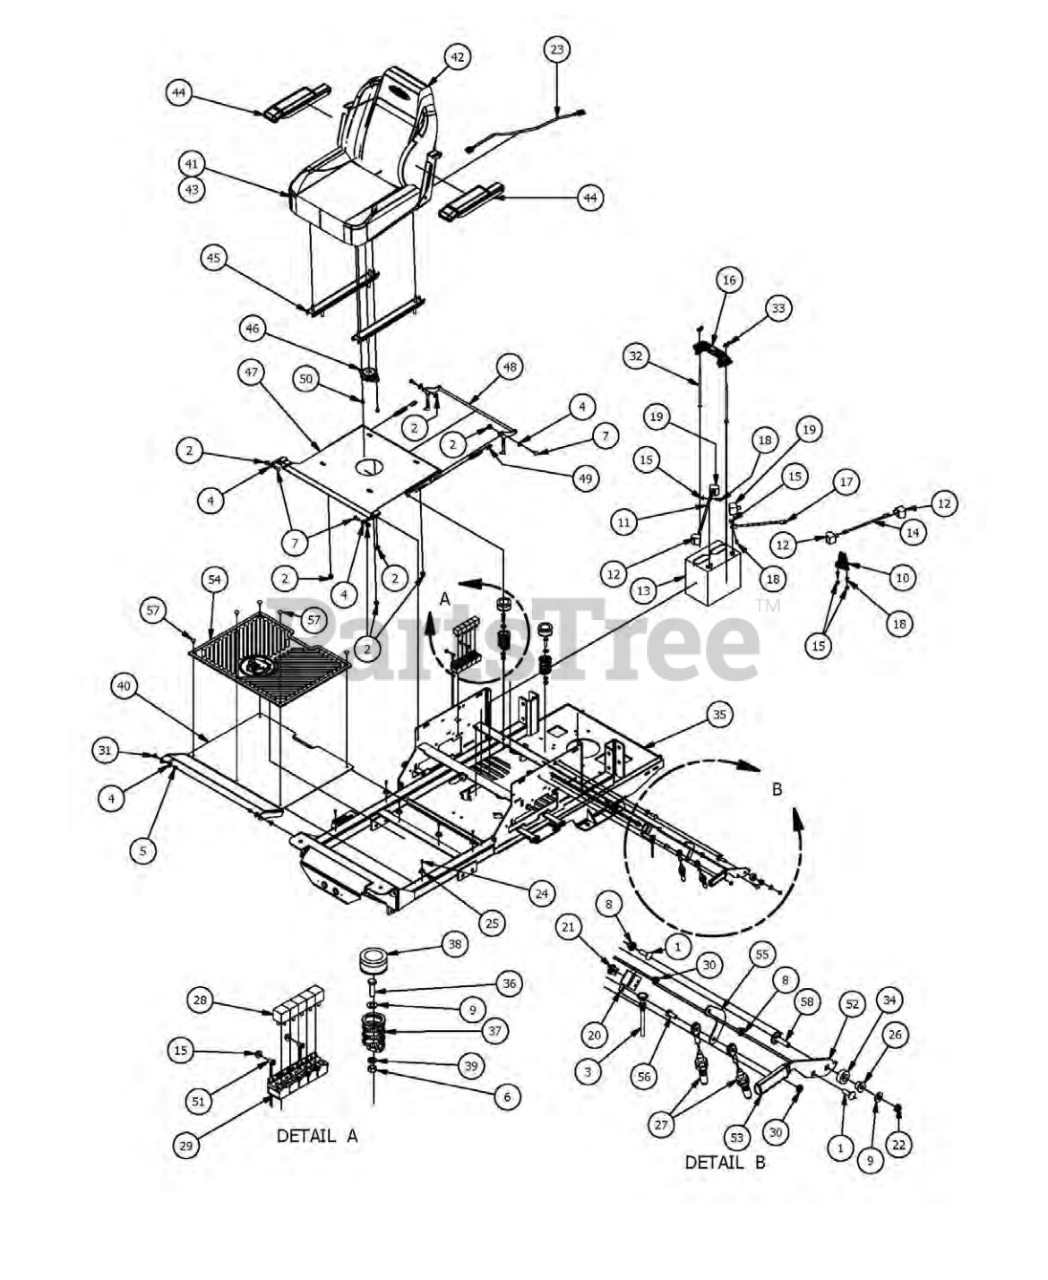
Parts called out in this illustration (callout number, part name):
1	5/16" x 1" Carriage Bolt
2	5/16" Nylock Flange Nut
4	360 ID Plastic Washer
5	1/4" Nylock Nut
6	3/8-16 Hex Nuts Zinc
7	5/16" x 7/8" Camiage Bolt
8	5/16" Flange Nut
9	3/8" Flat Washer
11	24" Red Battery Cable
14	12 in red battery cable
15	1/4-20 Hex Flange Nuts Zinc w/Serrations
16	Battery Hold Down
17	Ground Cable
18	1/4" x 3/4" Hex Bolt
19	Black Boot For Ground Cable
20	Safety Switch
21	12-24x 1/2 HWH Bolt
22	3/8-16 Centerlock Half Nut
23	Seat Switch Adapter
24	#10 x 1/2" Self Tapping Screw
25	Button Bumper
26	Bronze Bushing SF-1220-8
27	Brake Cable
29	Wire Harness
30	5/16-18 Nylock Jam Nut 1/2 Nut
31	1/4" x 3/4" Carriage Bolt
32	1/4-20 X 8 Carriage Bolt
33	1/4" Wing Nut
34	2015 Brake Lever Spacer
35	2016 Frame
36	3/8" x 1 1/4" Hex Bolt
37	Seat Spring
38	Seat Spring Cap Cover
39	3/8" Lock Washer
40	Maverick Floorboard
42	Back Cushion
43	Bottom Cushion
45	Seat Ralls
46	Seat Safety Switch
47	Seat Plate 2016
48	Seat Latch Rod Assembly 2016 Models
49	Seat Latch Spring
50	1/4-20x1/2 HWH Bolt Slot
51	1/4" x 1/2" BS C/S 18-8 SS
52	Brake Handle Cam Over
53	Rubber Brake Grip-cZT/ZT 2013
54	Maverick Floor Mat
55	Brake Cable Adapter Bracket
56	5/16" x 3/4" Hex Bolt
57	5/8" Christmas Tree Fastener
58	3/8" x 1-1/4" Carriage Bolt
